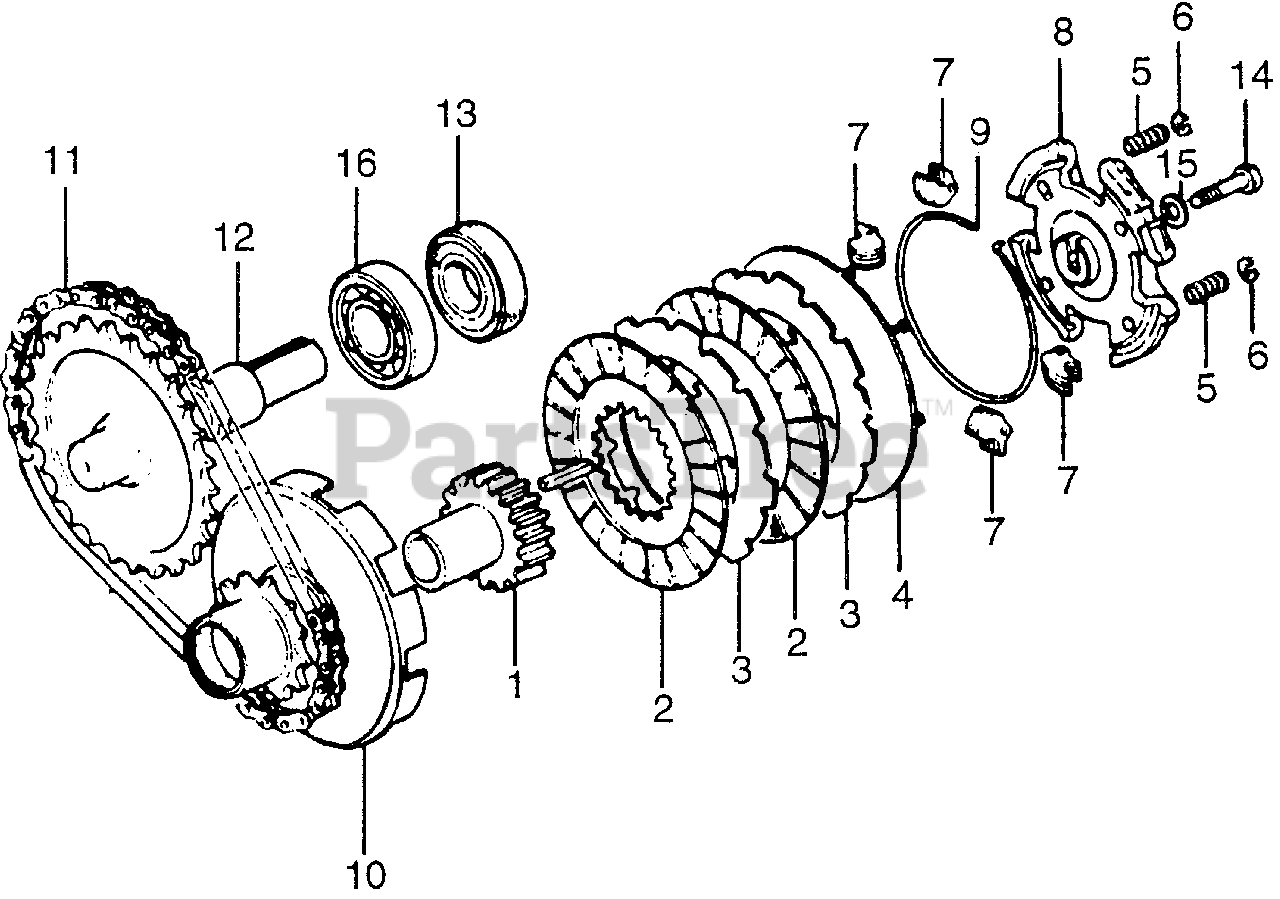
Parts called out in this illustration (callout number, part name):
1	CENTER, CLUTCH (NOT AVAILABLE)
2	DISK, CLUTCH FRICTION
3	PLATE, CLUTCH
4	PLATE, CLUTCH PRESSURE
5	SPRING, CLUTCH FREE
6	HOLDER, CLUTCH SPRING
7	WEIGHT, CLUTCH
8	HOLDER, CLUTCH WEIGHT (NOT AVAILABLE)
9	CENTER, CLUTCH WEIGHT
10	SPROCKET, DRIVE
11	CHAIN, DRIVE (RK428SH-36LE)
12	SHAFT, P.T.O. (28T)
13	OIL SEAL (PJ30507)
14	BOLT, HEX. (8X35)
15	WASHER, SPRING (8MM)
16	BEARING, RADIAL BALL (6205)
